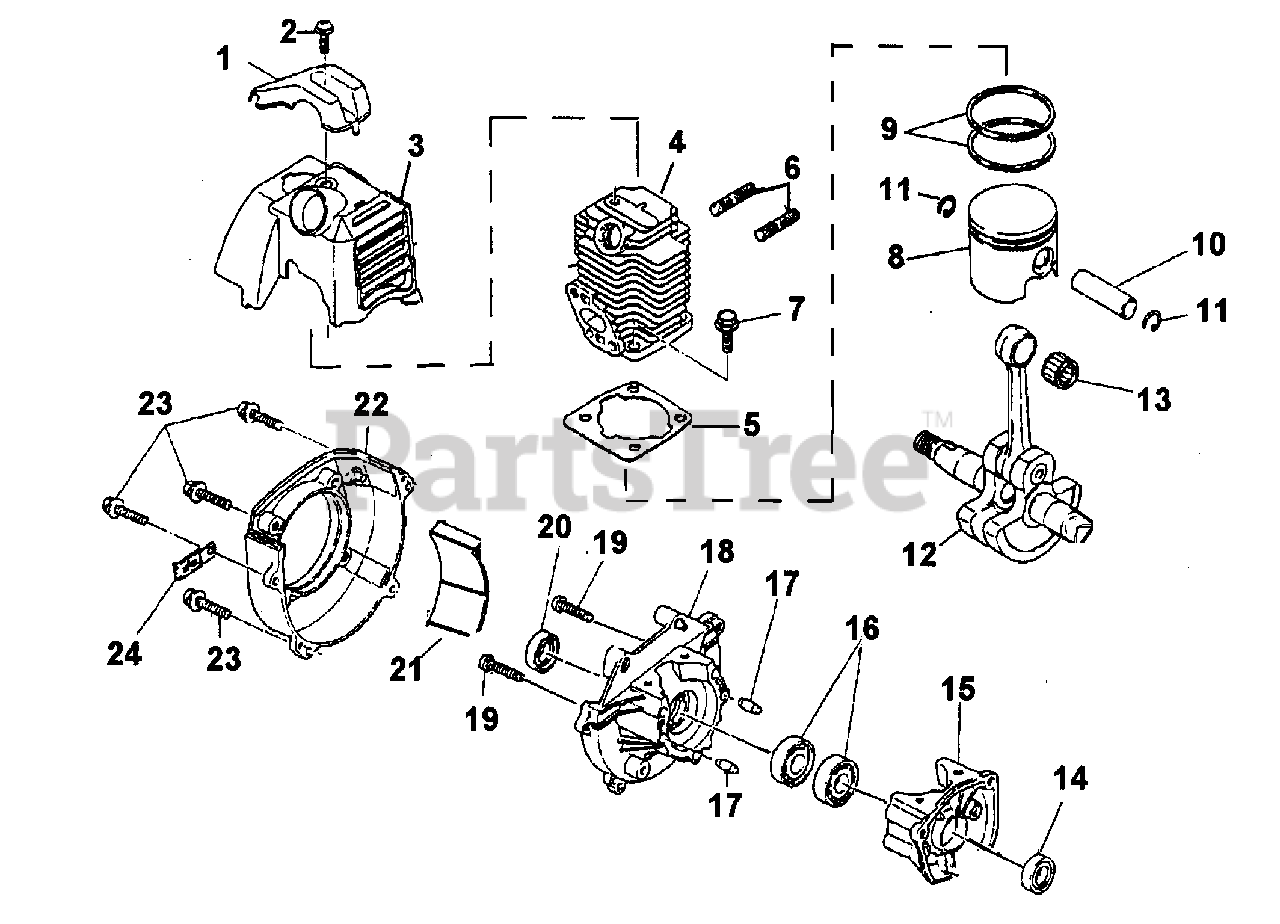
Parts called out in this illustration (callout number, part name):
1	GUARD, PLUG
2	SCREW & WASHER
3	COVER, TOP
4	CYLINDER ASSY.
5	GASKET, CYLINDER
6	BOLT, STUD
7	BOLT & WASHER
8	PISTON ASSY
9	RING, TOP
10	PIN, PISTON
11	CLIP, PISTON PIN
12	CRANKSHAFT ASSY.
13	BEARING, NEEDLE
14	OIL SEAL
15	CASE, STARTER
16	BEARING, BALL
17	PIN, DOWEL
18	CASE, DRIVE
19	SCREW, PAN HEAD
20	OIL SEAL
22	CASE, FAN
23	BOLT & WASHER
